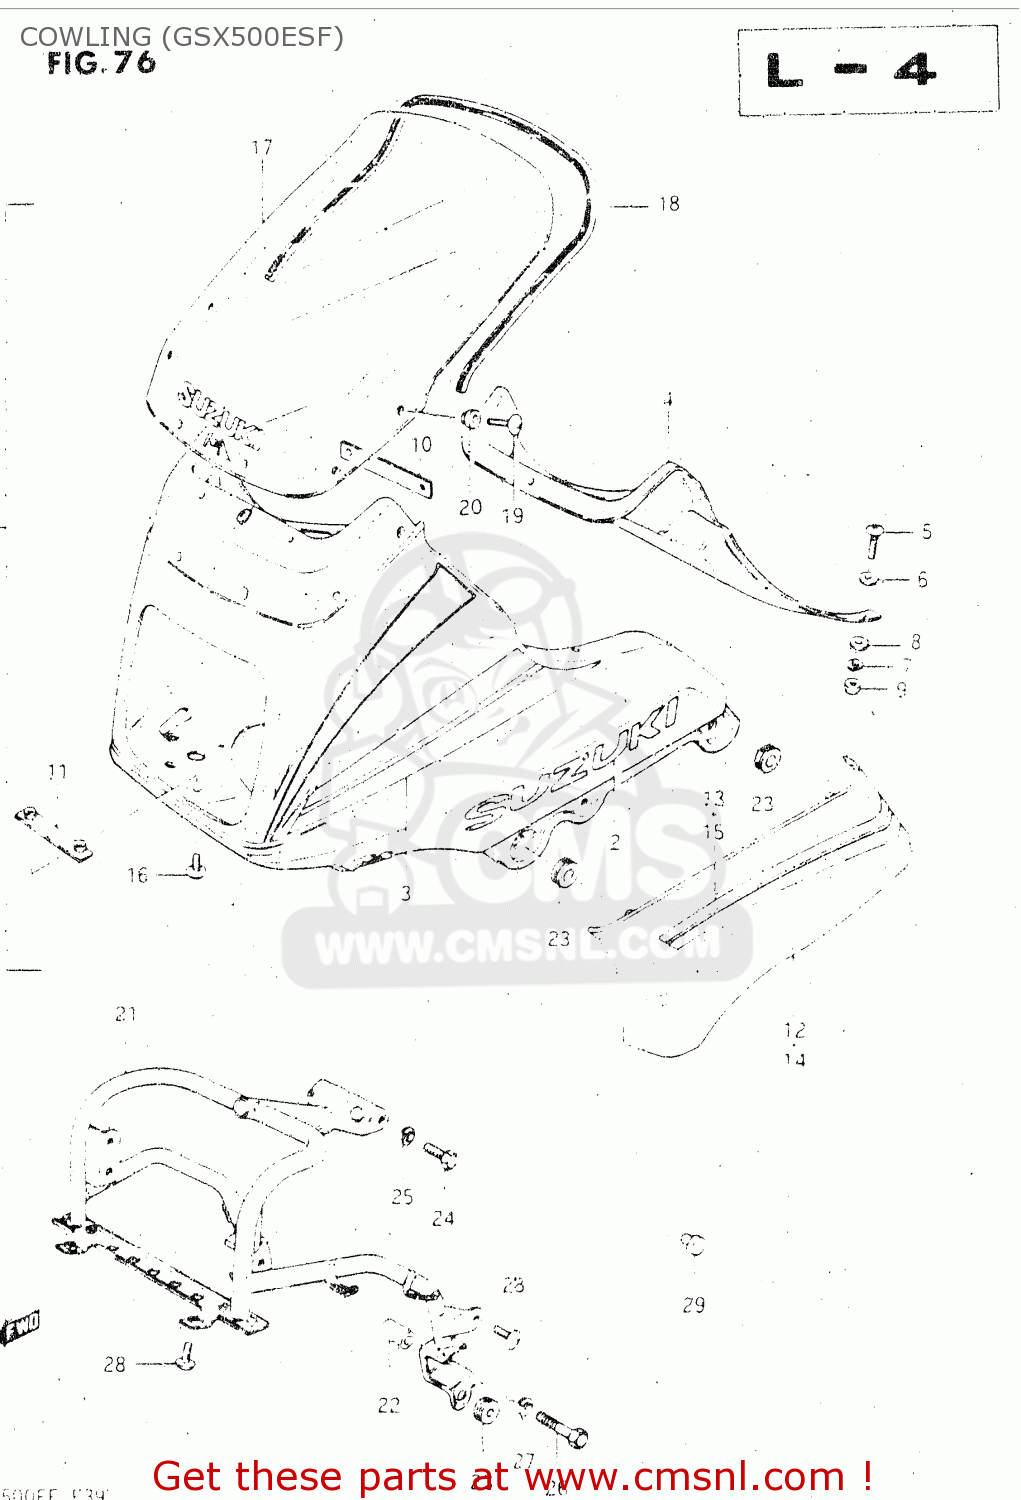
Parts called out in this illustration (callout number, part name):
1	COWLING ASSEMBLY
2	EMBLEM
3	TAPE SET
4	PANEL,COWLING,UPPER
5	SCREW
6	WASHER,5MM
7	WASHER,LOCK
8	WASHER,5MM
9	NUT ,5MM
10	BRACKET,COWLING,UPPER
11	BRACKET,COWLING,LOWER
12	COVER,COWLING,RIGHT
13	TAPE SET
14	COVER,COWLING
15	TAPE SET
16	SCREW
17	WINDOW
18	MOLDING,LOWER
19	SCREW
20	CUSHION
21	BRACE,COWLING
22	SPACER (8.2X12.5X23.5)
23	CUSHION
24	BOLT
25	WASHER,LOCK,8.
26	BOLT
27	WASHER,LOCK,8.
28	SCREW 6X12
29	PLUG
